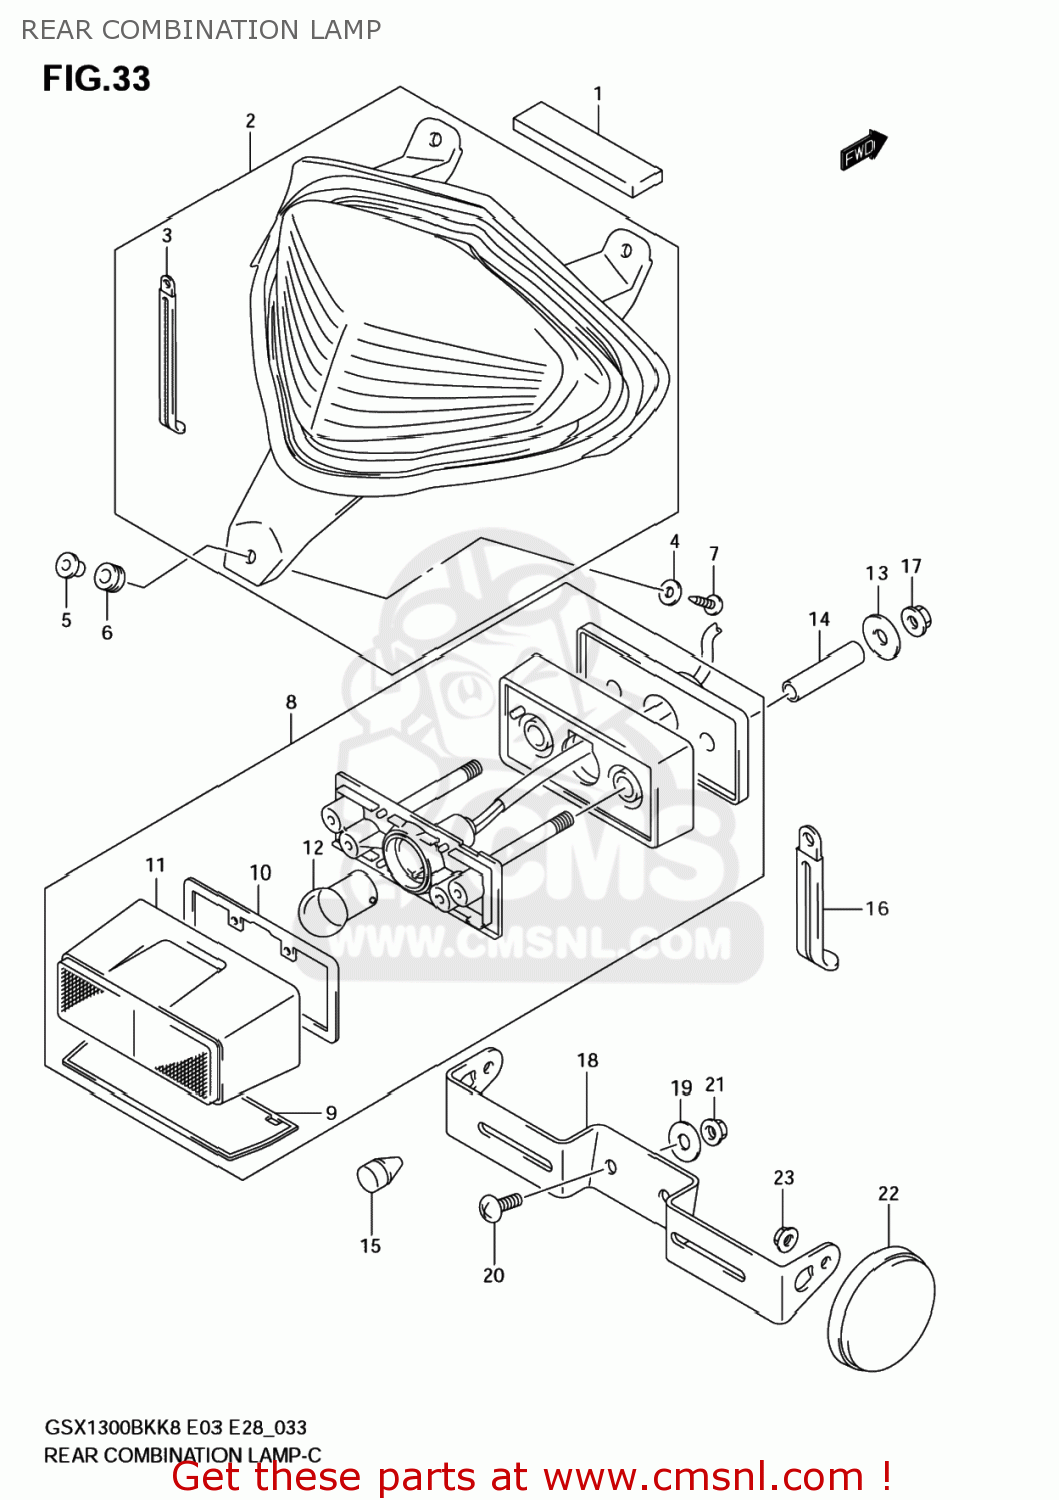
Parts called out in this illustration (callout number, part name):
1	CUSHION(75X20X10)
2	LAMP ASSY,RR COMBINATION
3	CLAMP(L:80)
4	WASHER(6.5X14X2)
5	WASHER
6	CUSHION
7	SCREW
8	LAMP ASSY,LICE
9	LENS LICENCE
10	GASKET (NAS)
11	COVER,LICENSE LAMP
12	BULB(12V5W,BF150-40160A)
13	WASHER(6.5X20X1.2)
14	SPACER(6.5X9X34)
15	CUSHION
16	CLAMP(L:45)
17	NUT
18	BRACKET,LICENSE PLATE
19	WASHER(6.5X16X1.2)
20	SCREW
21	NUT
22	REFLECTOR ASSY,RR SIDE
23	NUT
